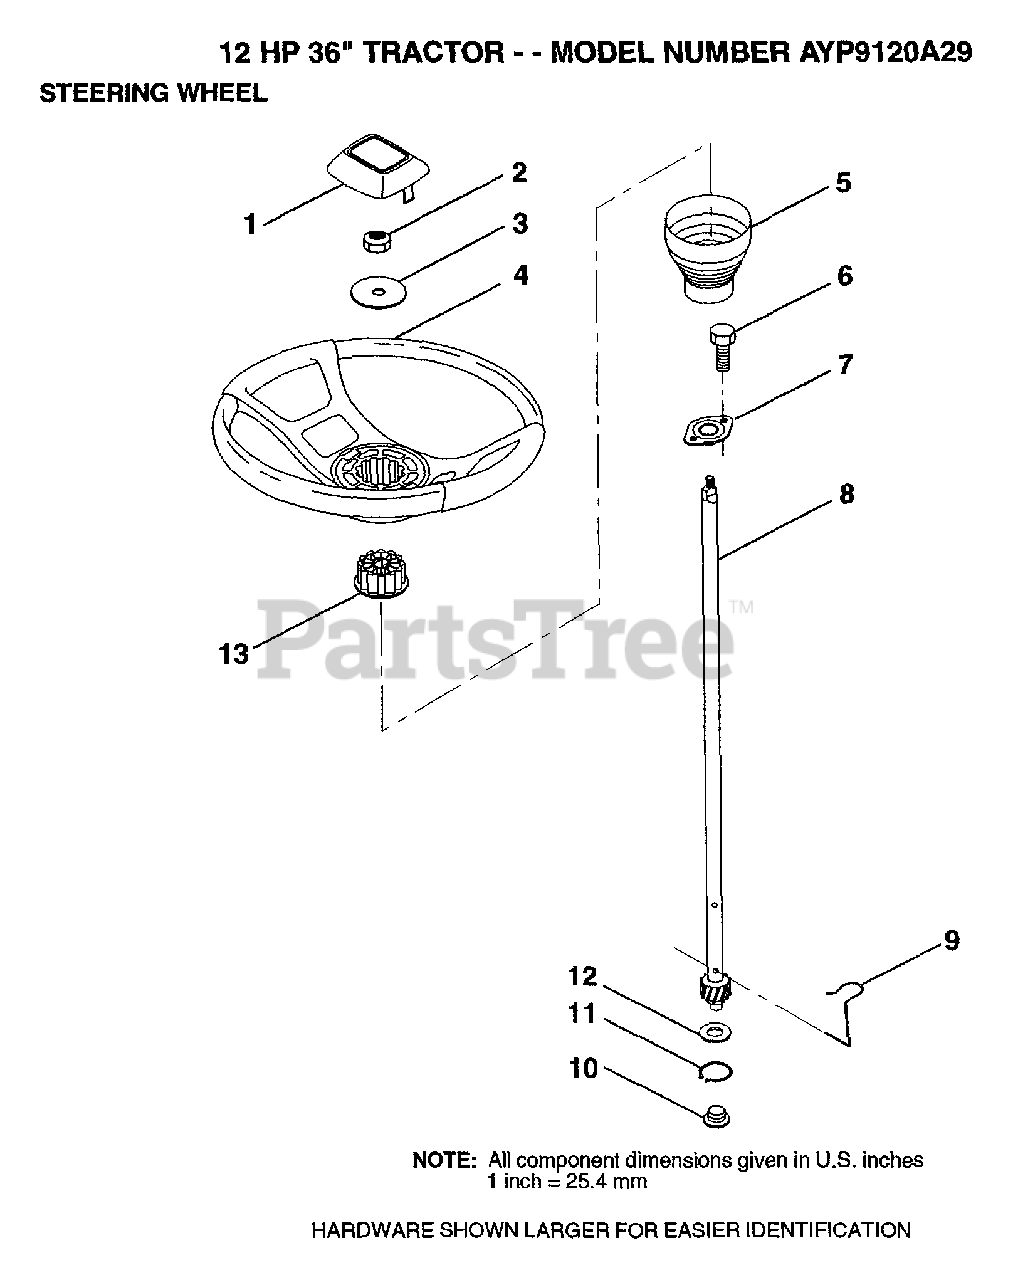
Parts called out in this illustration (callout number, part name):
1	ST WHL INSERT CAP
2	GRIPCO NUT
3	WASHER T
5	SLEEVE STEERING
9	STEERING CLIP
10	BUSHING STEER LWR
11	RING
12	WASHER LT
13	ADAPTER-WHEEL LT
